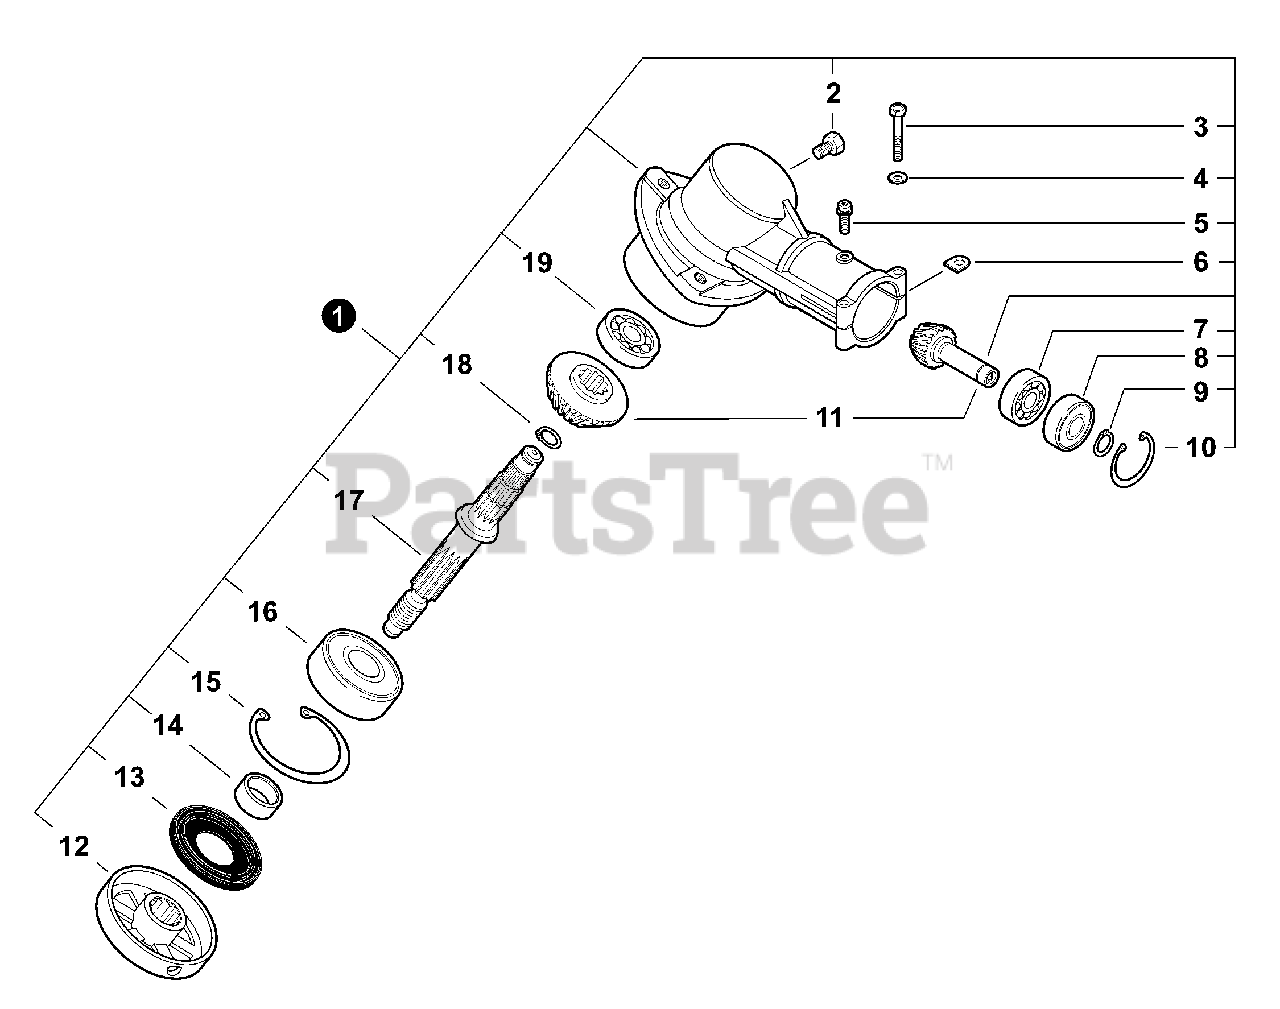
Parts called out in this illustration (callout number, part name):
1	GEAR CASE ASY
2	BOLT - 8×8
3	BOLT - 5×35
5	SCREW - 5×10
6	WASHER, SHIM
7	BEARING, BALL - 6900
8	BEARING, BALL - 6900Z
9	RING, RETAINING - 10
10	RING, RETAINING - 22
11	GEAR SET - BEVEL
12	ADAPTER, BLADE - UPPER
13	SEAL, OIL
15	RING, RETAINING - 32
16	BEARING, BALL - 6201
17	GEAR, SHAFT
18	RING, RETAINING - 12
19	BEARING, BALL - 609
